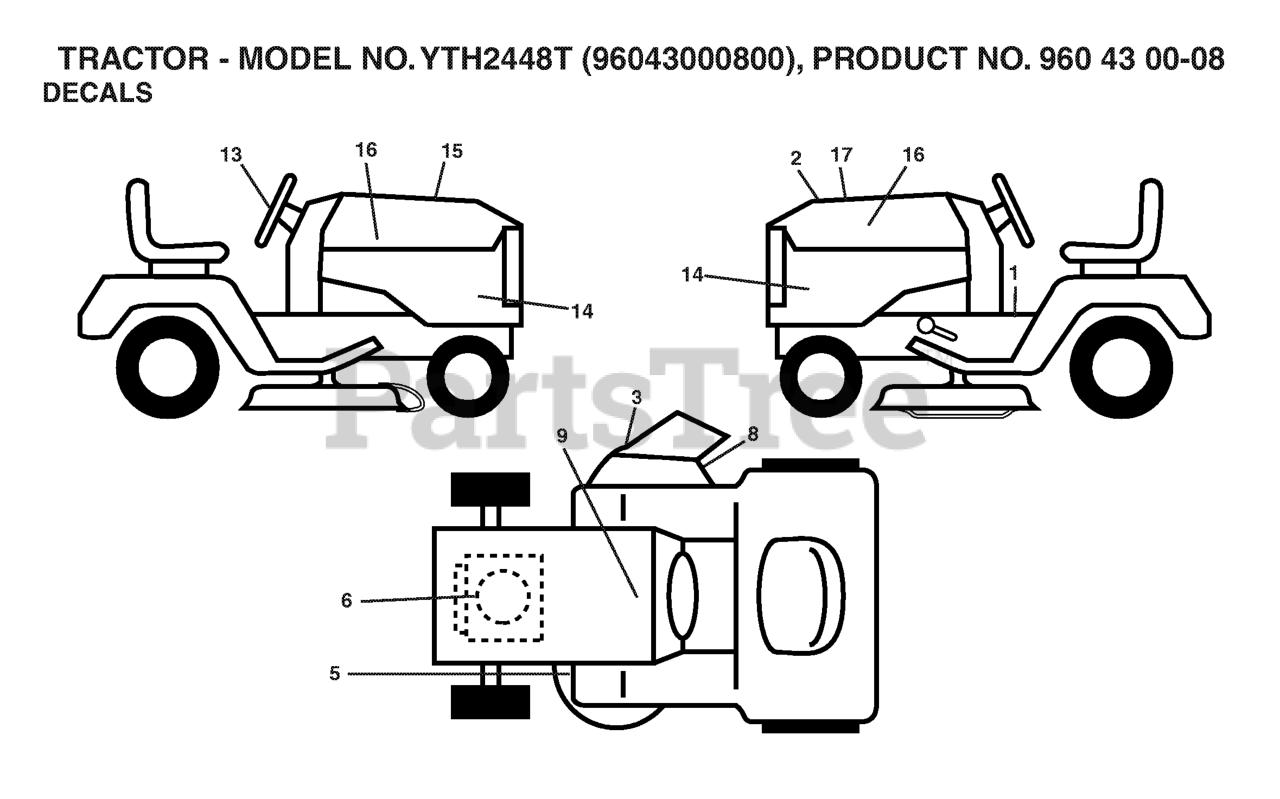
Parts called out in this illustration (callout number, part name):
2	DECAL.HOOD.TOP.INSERT.
3	DECAL.WARN.KEEP.HAND.AWAY
5	DECAL CLUTCH/BRAKE
8	DECAL.MOWER.SCH.48/54
9	DECAL BTRY SYMBOLS
13	DECAL.STEERING.HUSQ.BLUE
15	DECAL HOOD CUST. RESP.
16	DECAL.HOOD.NAMELOGO.HUSQ
